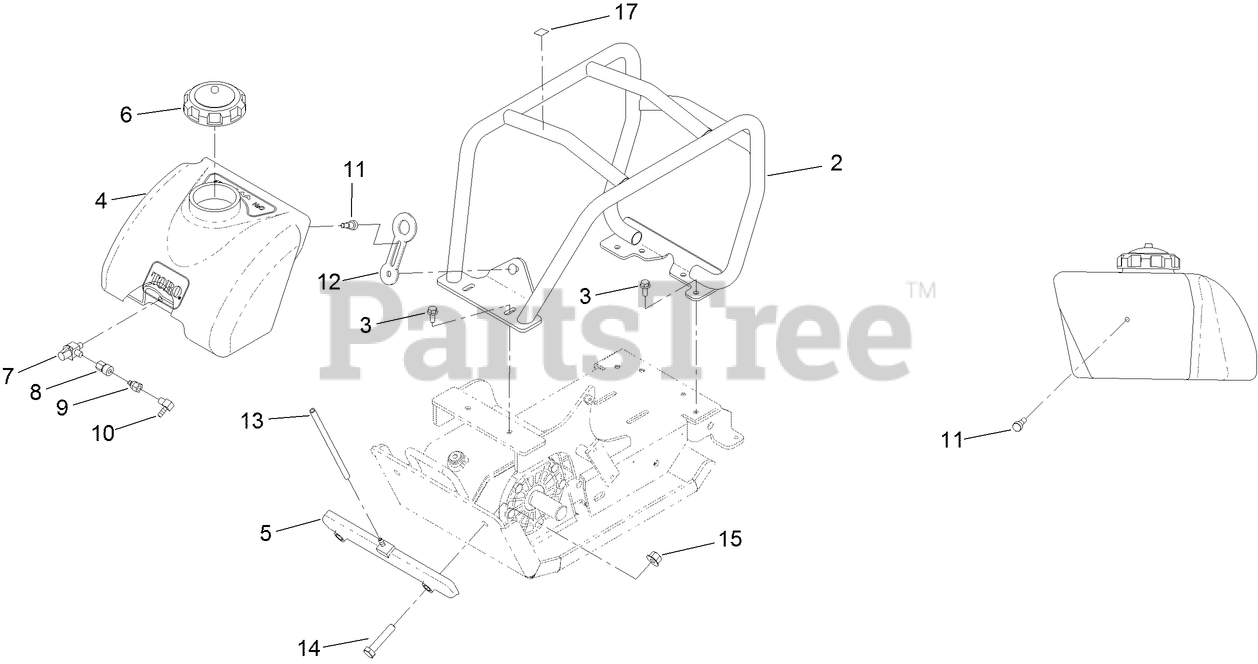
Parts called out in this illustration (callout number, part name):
2	CAGE-ROLL
3	SCREW-HHF
4	TANK-WATER
5	SPRINKLER
6	CAP-PLASTIC
7	VALVE-BALL
8	FITTING-QUICK, FEMALE
9	FITTING-QUICK, FEMALE, NIPPLE
10	FITTING-HYD, 90 DEG
11	SCREW-HSBH
12	LATCH-RUBBER
13	HOSE-WATER
14	SCREW-HH
15	NUT-LOCK, HHF
17	DECAL-POINT, LIFT
